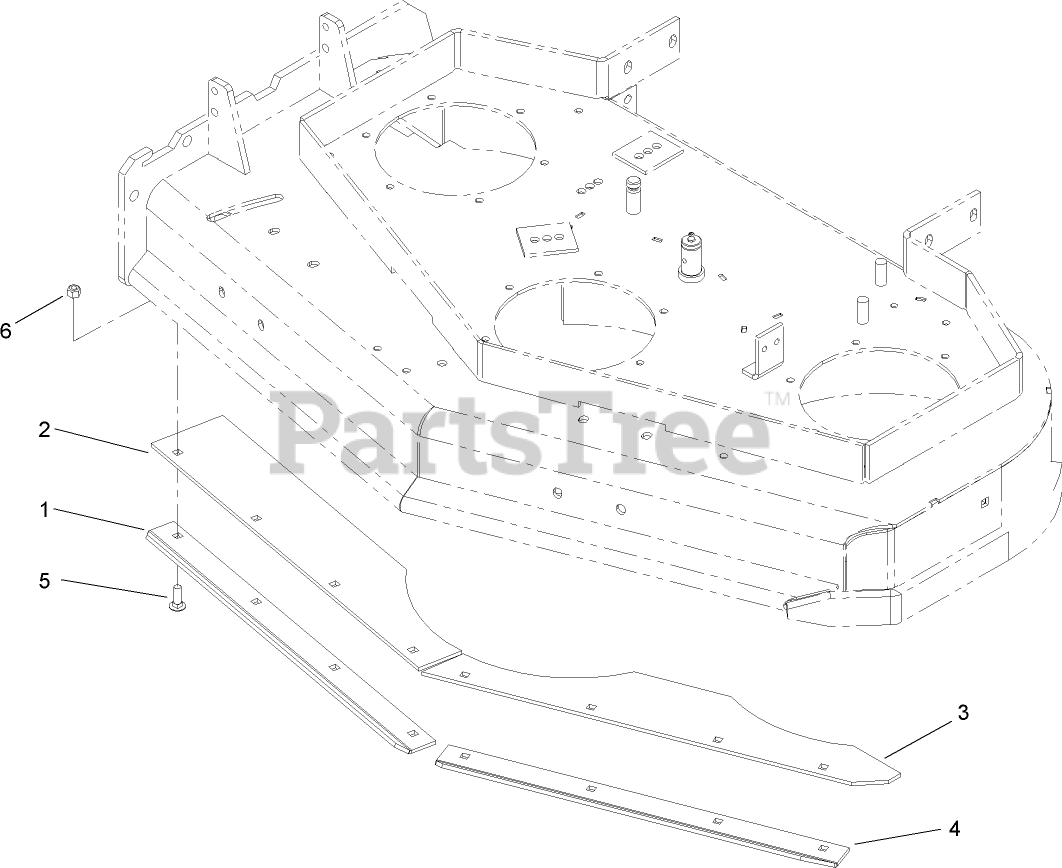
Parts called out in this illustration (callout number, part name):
1	SKID-SKIRT
2	SKIRT-RUBBER
3	SKIRT-RUBBER
4	SKID-SKIRT
5	BOLT-CARR
6	NUT-LOCK, NI
